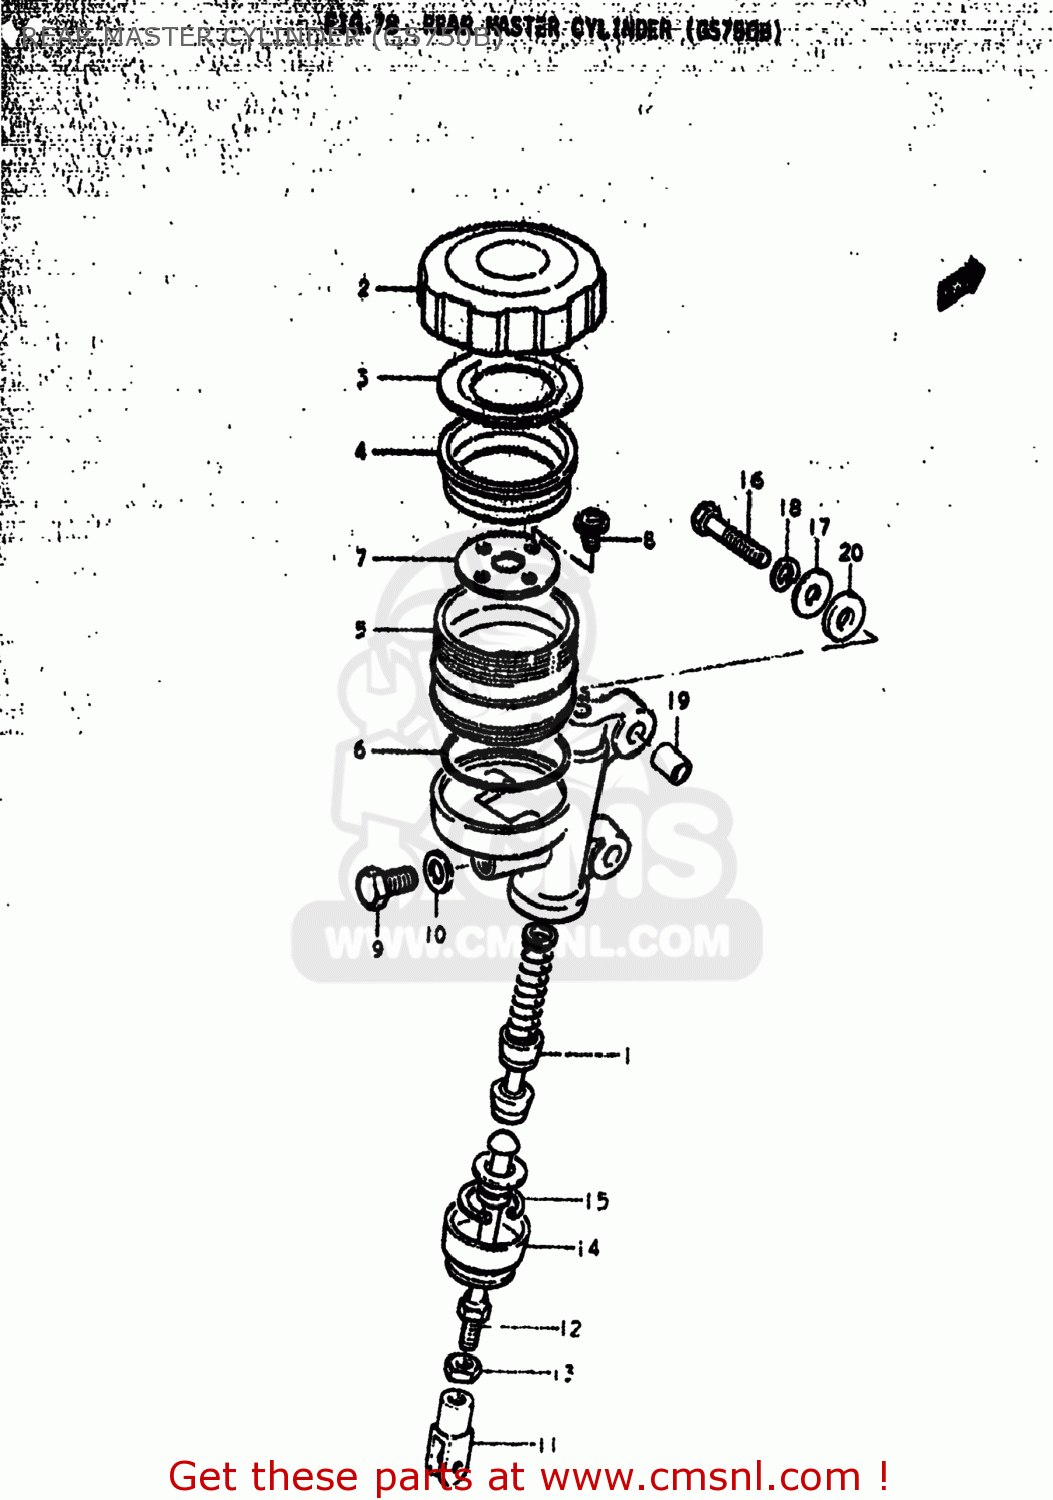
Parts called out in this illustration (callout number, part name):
1	PISTON/CUP SET
2	CAP
3	PLATE,DIAPHRAGM
4	DIAPHRAGM
5	RESERVOIR,MASTER CYLINDER
6	O RING
7	PLATE
8	SCREW,MASTER CYLINDER
11	YOKE
12	ROD,PUSH
13	NUT
14	BOOT
15	CIRCLIP
16	BOLT
17	WASHER (8.2X20X1.6)
18	LOCK WASHER
19	SPACER(8.5X12X19)
20	CUSHION
